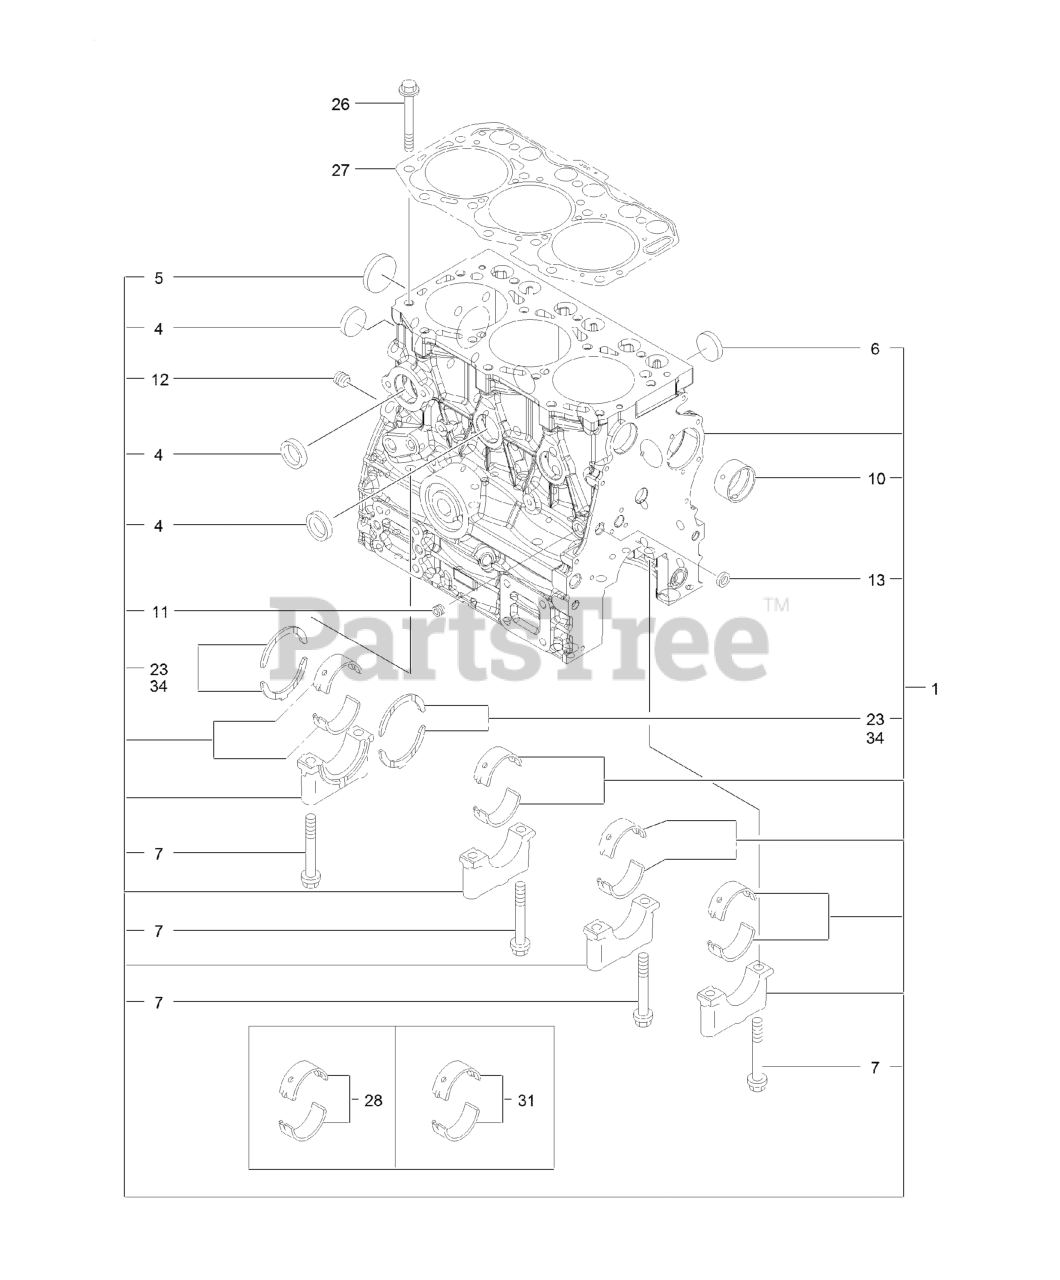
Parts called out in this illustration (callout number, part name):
1	BLOCK ASM-CYLINDER
4	PLUG, CUP TYPE 30
5	PLUG-DISH
6	PLUG-CUP TYPE 25
7	BOLT-METAL CAP
10	BUSH-CAMSHAFT
23	BEARING ASSY-THRUST
26	BOLT, CYLINDER HEAD
27	GASKET SET-HEAD
28	BEARING ASSY-MAIN
31	BEARING ASSY-MAIN
34	BEARING-THRUST
